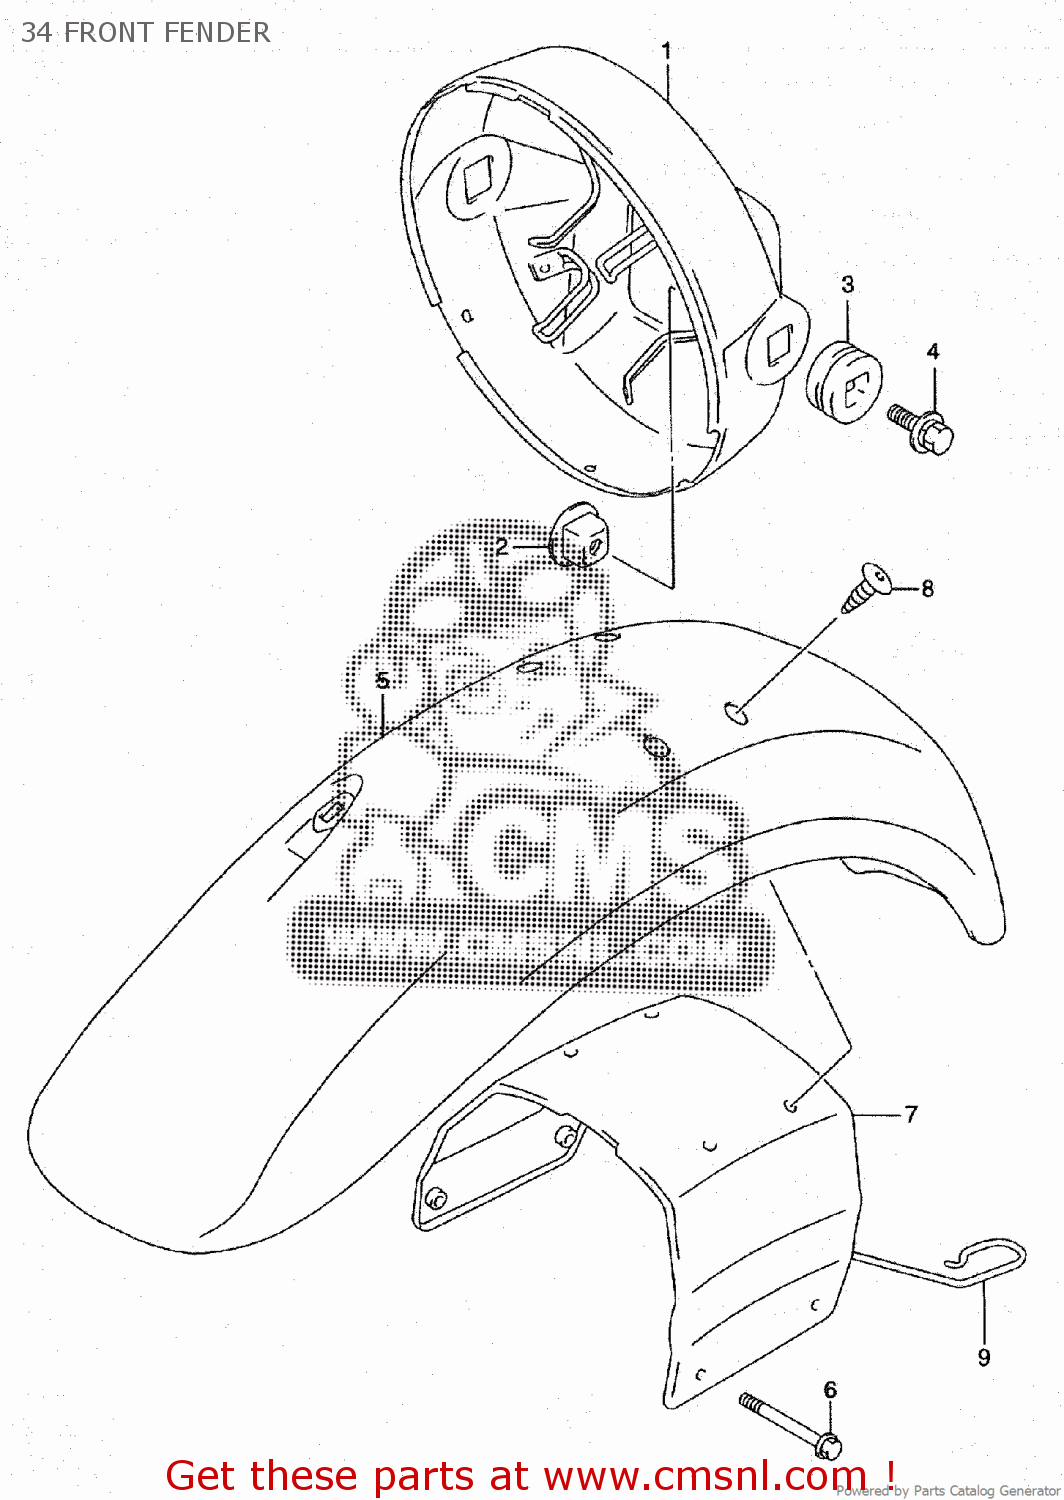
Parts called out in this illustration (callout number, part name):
1	HOUSING,HEADLAMP (COWLING)
2	SPACER,HEADLAMP HOUSING
3	CUSHION,HEADLAMP HOUSING
4	BOLT
5	FENDER,FR
6	BOLT
8	SCREW(5X16)
